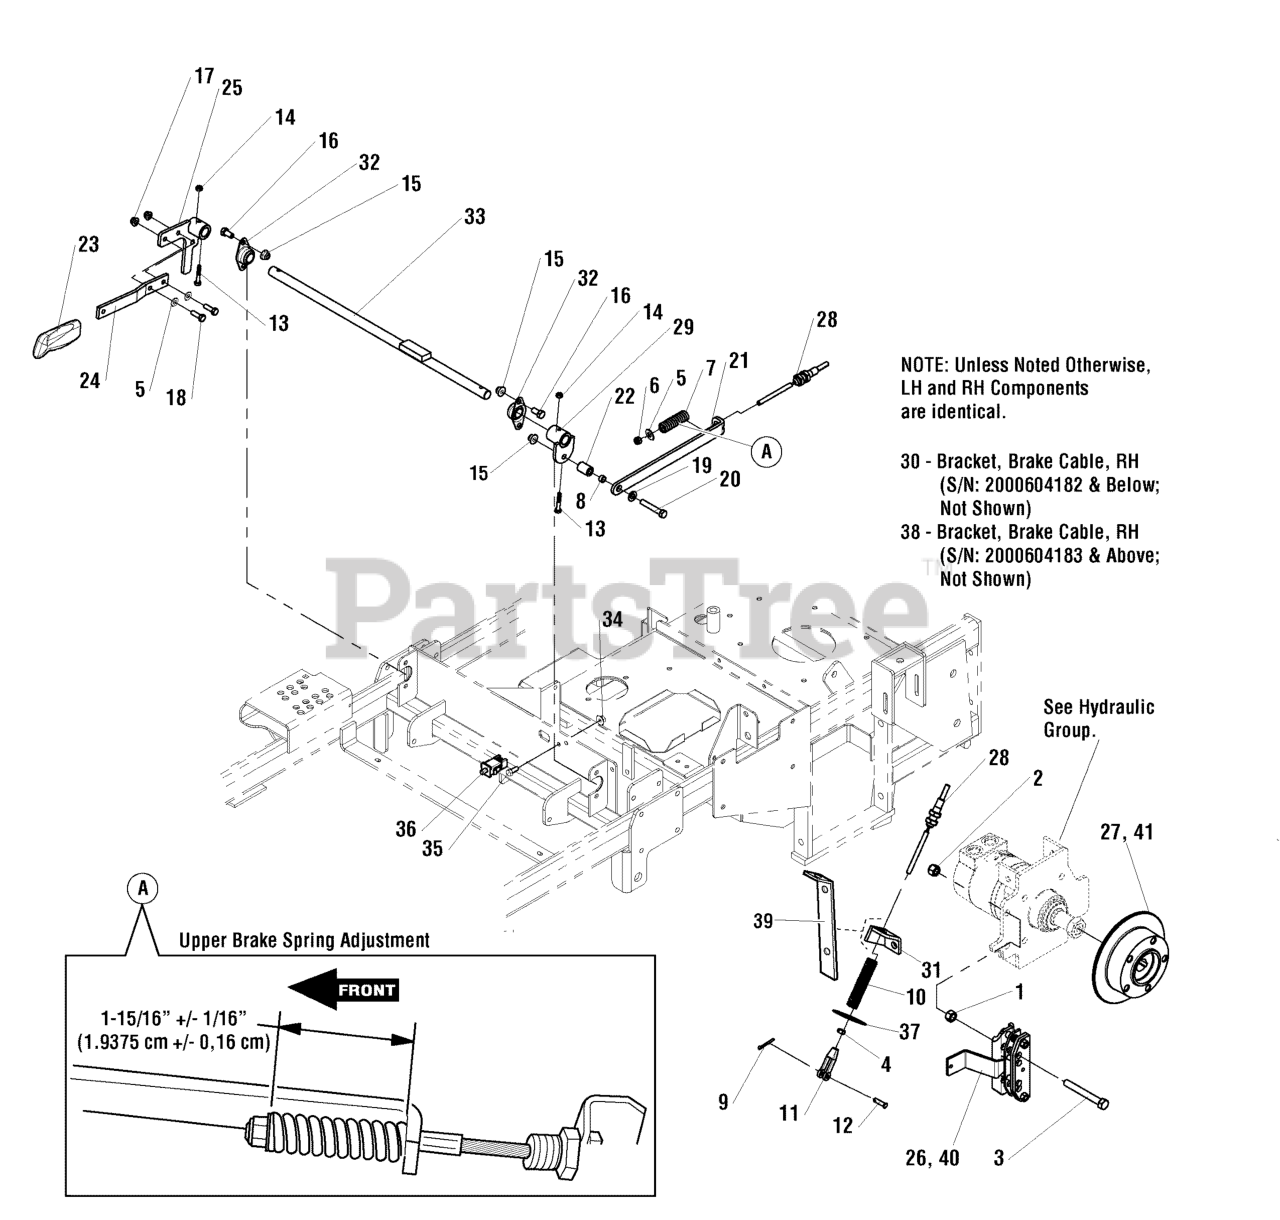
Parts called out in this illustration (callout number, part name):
1	NUT, 1/2-13 HEX JAM
2	NUT, 1/2-13 HEX NYLON LOCK
3	BOLT, 1/2-13 X 4" GD5 CZ
4	NUT, 5/16-24 HEX
5	WASHER, 5/16" SAE
6	NUT, 5/16-24 HEX NYLON LOCK
7	SPRING, BRAKE
8	SPACER, .38 X .50 X .27
9	PIN, COTTER, 1/8 X 1-1/4
10	SPRING, COMPRESSION
11	CLEVIS, 5/16-24, STEEL, CLEAR ZINC
12	PIN, CLEVIS, 5/16" X 1
13	BOLT, 1/4-20 X 1-1/2", GD5
14	NUT, 1/4-20 HEX SIDE LOCK
15	NUT, 3/8-16 HEX NYLOCK FLANGE
16	BOLT, 3/8-16 X 3/4" GD5 CZ
17	NUT, 5/16-18 HEX NYLOCK FLANGE
18	BOLT, 5/16-18 X 1" GD5 YZ
19	WASHER, 3/8 SAE
20	BOLT, 3/8-16 X 2-1/4" GD5 CZ
21	BRAKE LINKAGE - BLK
22	SPACER, .39 X .75 X 1.06
23	GRIP, BLACK FLEXIBLE
24	HANDLE, BRAKE LEVER - BLK
25	WELD, BRAKE HANDLE MOUNT - BLK
26	CALIPER, MECHANICAL
27	WHEEL HUB, COMPACT CALIPER (86720)
28	CABLE, PARKING BRAKE
29	PIVOT, LINKAGE MOUNT WELDMENT - BLK
31	WELD, BRACKET, BRAKE CABLE, RH
32	BEARING, BRONZE FLANGE, 3/4
33	WELD, SHAFT BRAKE LEVER - BLK
34	NUT, 5/16-18 HEX SERRATED FLANGE (LARGE)
35	BOLT, 5/16-18 X 3/4 GD5
36	SWITCH, DP NO/NC SNAP-IN
37	WASHER, 5/16" FENDER
38	WELD, BRACKET, BRAKE CABLE, RH
40	COMPACT CALIPER, AUSCO
41	WHEEL HUB, COMPACT CALIPER (86720)
